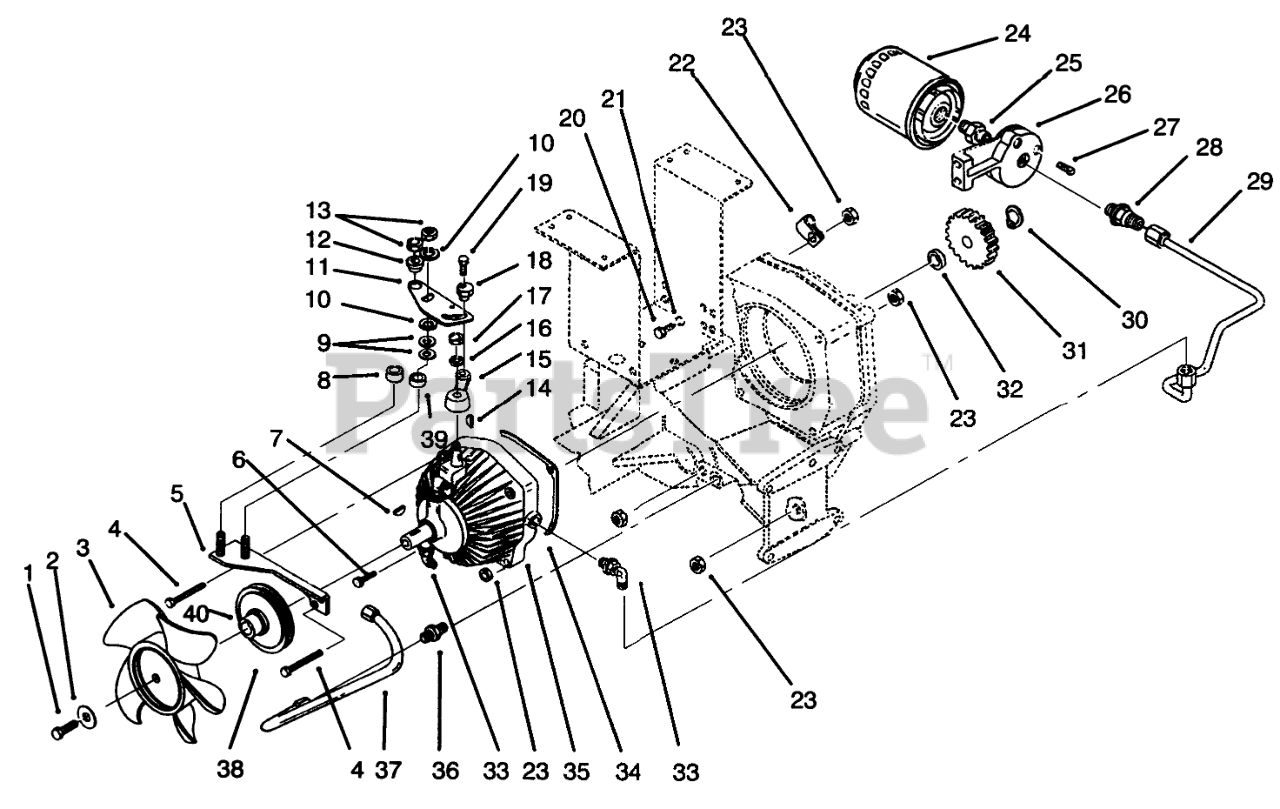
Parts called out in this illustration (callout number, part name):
1	SCREW-HEX HD CAP
2	WASHER
3	NYLON FAN-L-CW
4	SCREW-HH
5	ASSY-PLATE B
7	KEY-WOODRUFF
8	SPACER-PIVOT
9	WASHER-SPRING DISC
10	FRICTION WASHER
11	CAM-SPEED CONTROL (NS)
12	CAM-SPACER
14	KEY-WOODRUFF
15	ARM-SPEED CONTROLB
16	WASHER-FLAT
17	NUT-LOCK, NI
19	Screw-HH
20	SCREW-HH
21	WASHER-LOCK
22	CLIP
23	NUT-LOCK, NI
24	OIL FILTER ASM
25	FITTING
26	BASE-FILTER
28	Fitting-Hyd., Straight (Incl. "O" Ring)
29	ASS'Y-TUBE FILTER
30	RING-SNAP, EXTERNAL
31	GEAR 20 TEETH DRIVE
32	SPACER GEAR
33	ELBOW
34	GASKET
35	Pump & Motor
36	FITTING-TUBE
37	ASSY-TUBE SUCTION
38	PULLEY
39	SPACER-FRICTION
